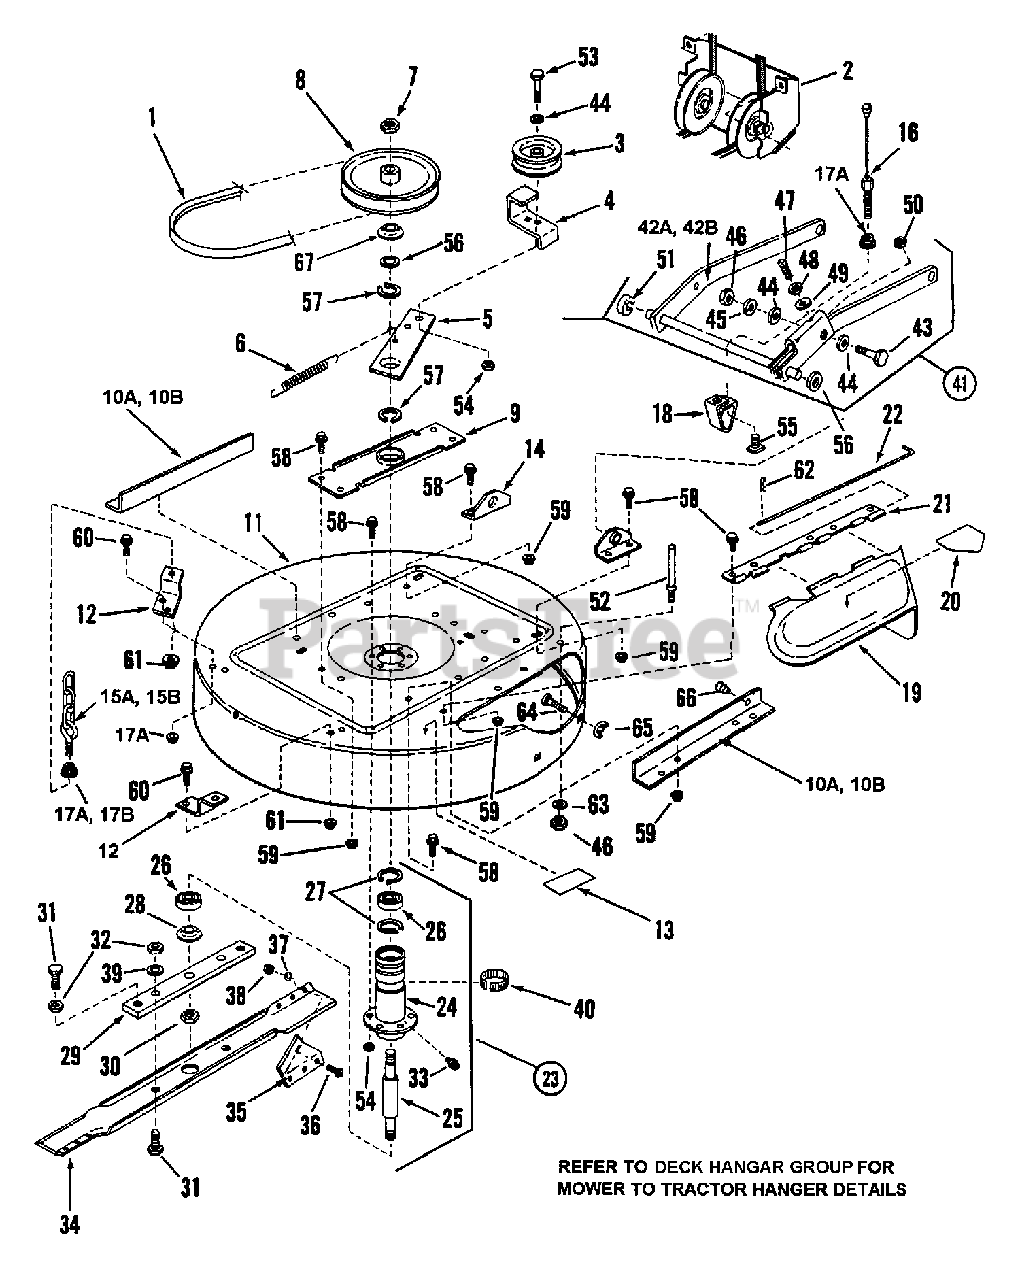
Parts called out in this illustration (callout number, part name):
1	BELT, 33" Mower Drive (A-897 Kevlar cord)
2	ASSEMBLY, Mule Drive
3	PULLEY, Idler (Flat)(4.120.D.)
4	GUIDE, Belt
5	ARM, Idler
6	SPRING, Belt Tension
7	NUT, 3/4-16 Hex Jam
8	PULLEY, 8" O.D.
9	BRACE, Spindle
10A	RAIL, Side (NLA)(use 7038194 and drill as needed)
10B	RAIL, Kit Side '85
11	DECK, 33" Cutter
12	BRACKET, Rear Lift (NLA)(use 7051533)
12	BRACKET, Rear Lift 3/8-16
13	DECAL, Caution, (Deflector/Adapter)
14	BRACKET, Front Hanger
15A	ASS'Y, 5/16 Bolt-Chain
15B	ASSEMBLY, 3/8 Bolt-Chain
16	CABLE, Front Lift, 8"
17A	NUT, 5/16-18 Hex Fl. Lock
17B	NUT, 3/8-16 Hex Jam
18	BRACKET, Front Lift Hanger
19	DEFLECTOR
20	DECAL, Danger (Cut Finger)
21	HINGE, Side Chute
22	PIN, Hinge
23	ASSEMBLY, Spindle
24	HOUSING, Spindle
25	SPINDLE, 33" Mower Deck, 7.75" Long
26	BEARING, Spindle
27	RING, Retaining
28	WASHER, Spindle
29	HOLDER, Blade
30	NUT, 5/8-18 Hex Ctr. Lock
31	SCREW, 1/2-20 x 1" Hex Head Cap, Grade 5
32	NUT, 1/2-20 Hex Jam
33	FITTING, Lube (Press fit for .187 hole-no ball)
34	BLADE, 33" Cutter Deck
35	KIT, Air Lift
36	SCREW, 5/16-24 Machine
37	WASHER, 5/16 Internal Tooth Lock
38	NUT, 5/16-24 Hex
39	WASHER, 1/2" Internal Tooth Lock
40	RING, Tolerance
41	ASSEMBLY, Front Lift Arm
42A	ARM, Front Lift
42B	ARM, Front Lift (1985)
43	SCREW, 3/8-24 x 1-1/4" Hex Head Cap, Grade.5
44	WASHER, 3/8" Flat
45	WASHER, 3/8 Split Lock
46	NUT, 3/8-24 Hex, Gr. 2
47	SETSCREW, 5/16-18x 1-1/4
48	NUT, 5/16-18 Hex Jam
49	WASHER, 5/16 Flat
50	NUT, 5/16-18 Hex
51	RING, White
52	STUD, Deck Stop
53	SCREW, 3/8-24 x 1-1/2" Hex Head Cap, Grade 2
54	NUT, 3/8-24 Hex Center Lock
55	T-NUT, 5/16-18
56	WASHER, Spacer
57	RING, 2" External Retaining
58	BOLT, 3/8-16 x 3/4" Hex Flange Lock Lock
59	NUT, 3/8-16 Hex Flange Lock
60	BOLT, 5/16-18 x 1/2" Hex Flange Lock Lock, Grade 5
61	NUT, 5/16-18 Hex Flange Top Lock
62	HAIRPIN, Cotter
63	WASHER, 3/8 Int. Tooth Lock
64	BOLT, 5/16-18 x 3/4" Short Neck Carriage, Grade 5
65	WING-NUT, 5/16-18
66	BUMPER BUTTON
67	WASHER, Spindle
